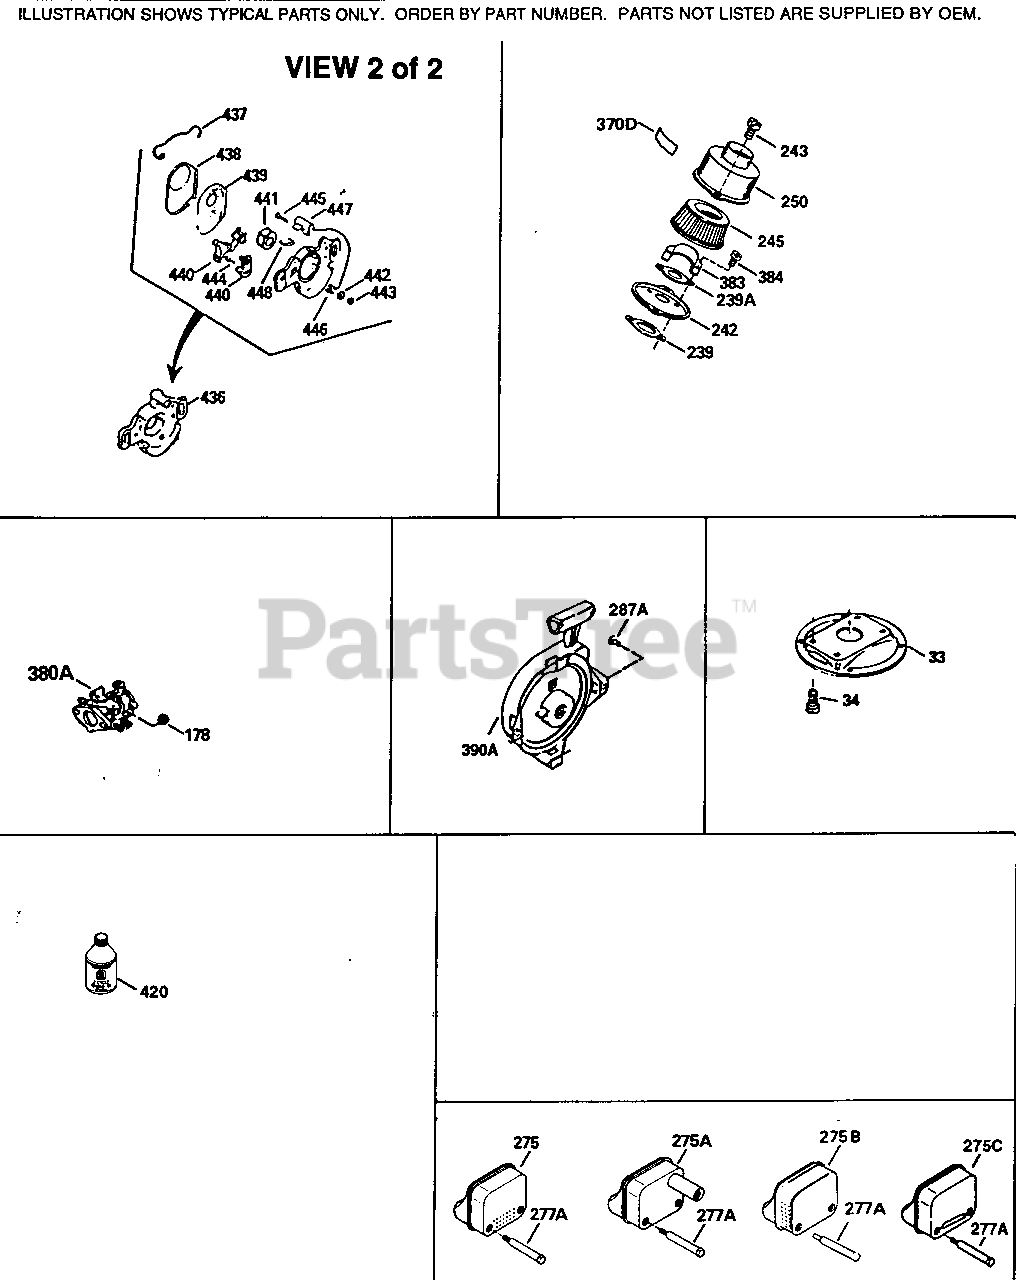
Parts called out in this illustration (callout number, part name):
130B	Screw, 1/4-20 x 1/2"
209	Screw, Torx T-25, 10-24 x 1/2"
275	Muffler (Incl. 274 & 277)
353A	Screw, Torx T-30, 1/4-20 x 3/4"
420	2-Cycle Oil with Fuel Stabilizer - 8 oz.
